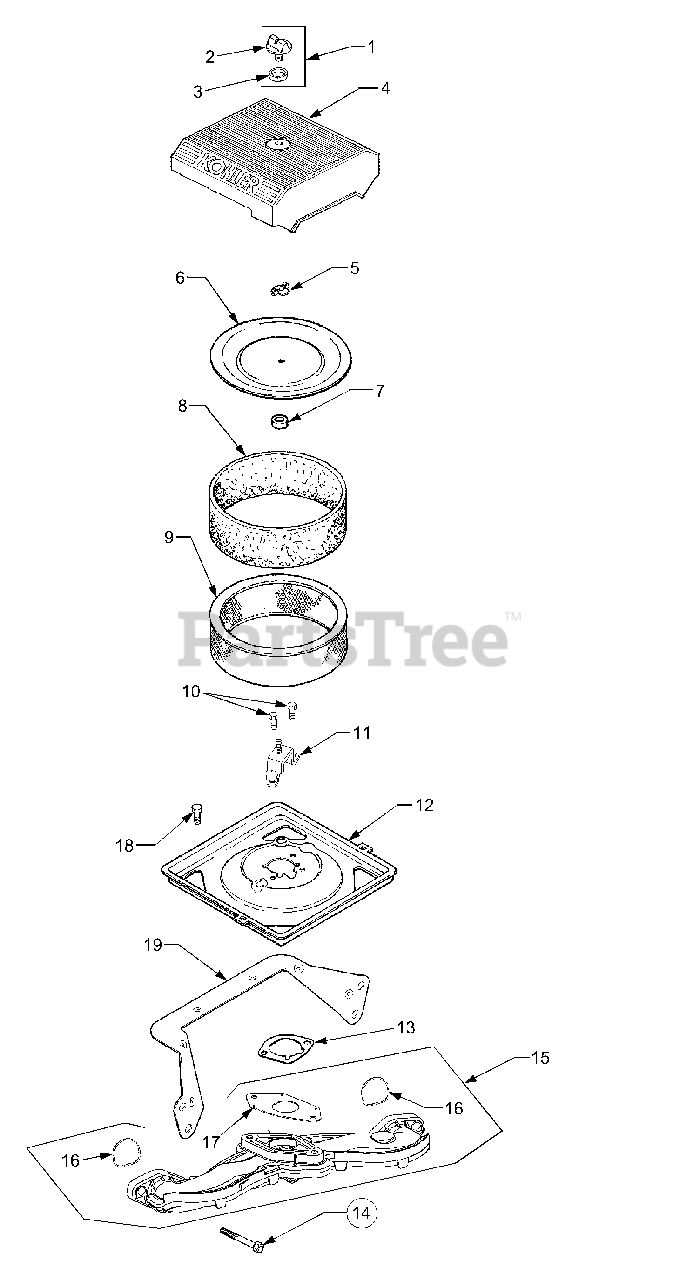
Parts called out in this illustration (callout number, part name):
1	Kit, Knob w/Seal
3	Seal, Air Cleaner Cover Knob
4	Cover, Air Cleaner
6	Cover, Inner Air Cleaner
7	Seal, Inner Air Cleaner
8	Precleaner, Element, 71mm deep
9	Element, Air Cleaner, 74mm deep
10	Screw, Hex Flange, M6 x 1.0 x16
11	Bracket, Air Cleaner Base
12	Base, Air Cleaner
13	Gasket, Air Cleaner Base
14	Screw, Hex Flange, M6 x 1.0 x 40
15	Manifold, Intake
16	O-Ring, Intake Manifold
17	Gasket, Carburetor
18	Screw, Hex Flng, M5 x 0.8 x 10
19	Bracket, Air Cleaner Base
